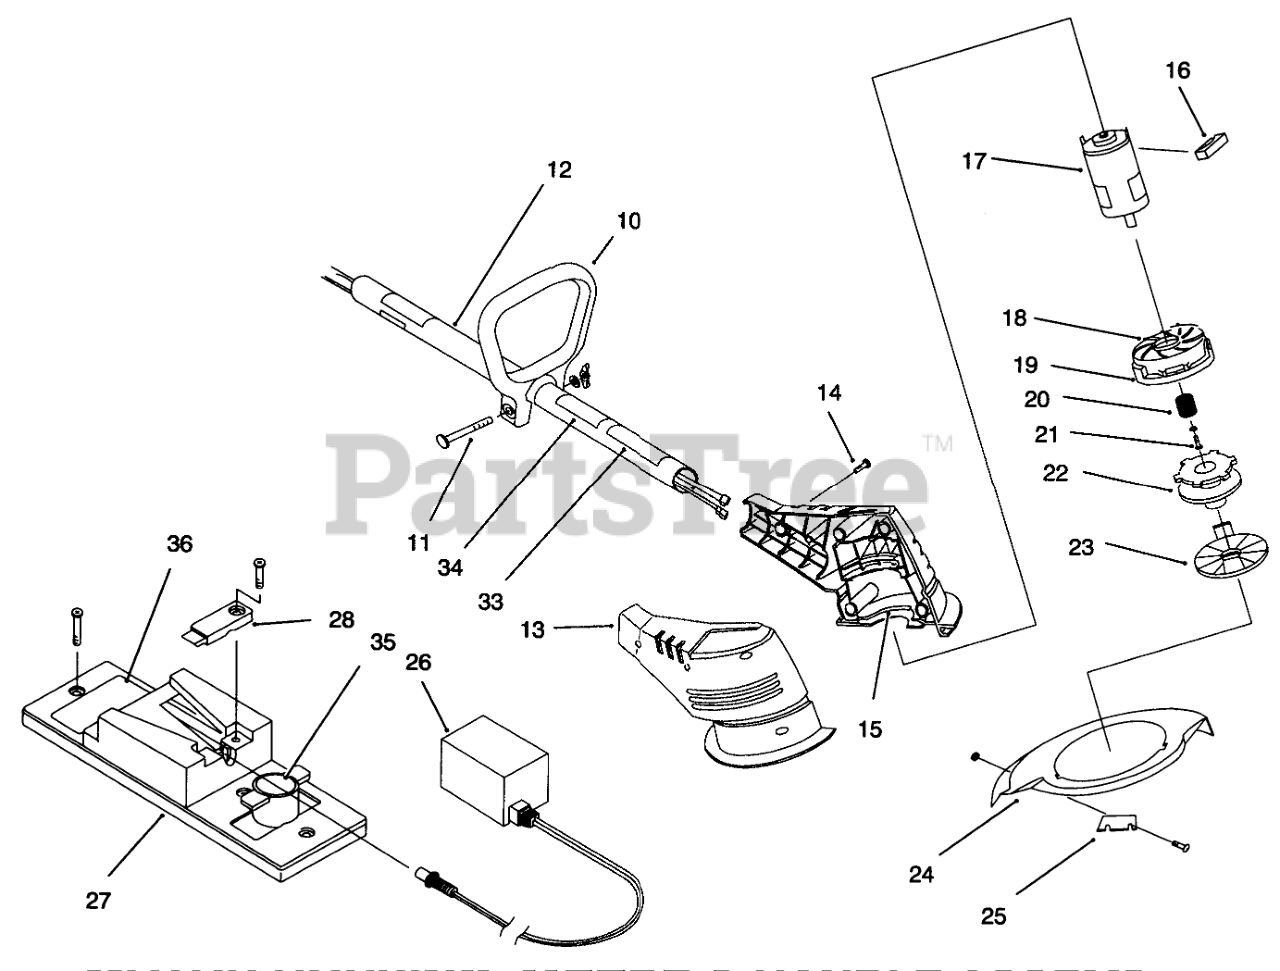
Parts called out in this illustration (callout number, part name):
10	D-HANDLE
11	HARDWARE - D-HANDLE
12	ASSEMBLY - BOOM
13	HOUSING - MOTOR
14	SCREW - HOUSING
15	SUPPORTS - MOTOR (3)
16	BLOCK - ANTI-ROTATION
17	MOTOR
18	Outer Spool and Eyelet (Incl. Ref. #19)
19	EYELET
20	SPRING
21	SCREW & WASHER
22	Inner Reel and .065 Line (15 ft.)
23	COVER - REEL
24	Guard and Blade Assembly (Inc. Ref. #25)
25	ASSEMBLY - BLADE
26	CHARGER - BATTERY
27	ASSEMBLY - WALL STATION
28	WALL STATION CLAMP/SCREW
33	Decal-Safety Symbol
34	DECAL - UL SAFETY WARNING
35	DECAL - TORO LOGO
36	Decal-Caution
